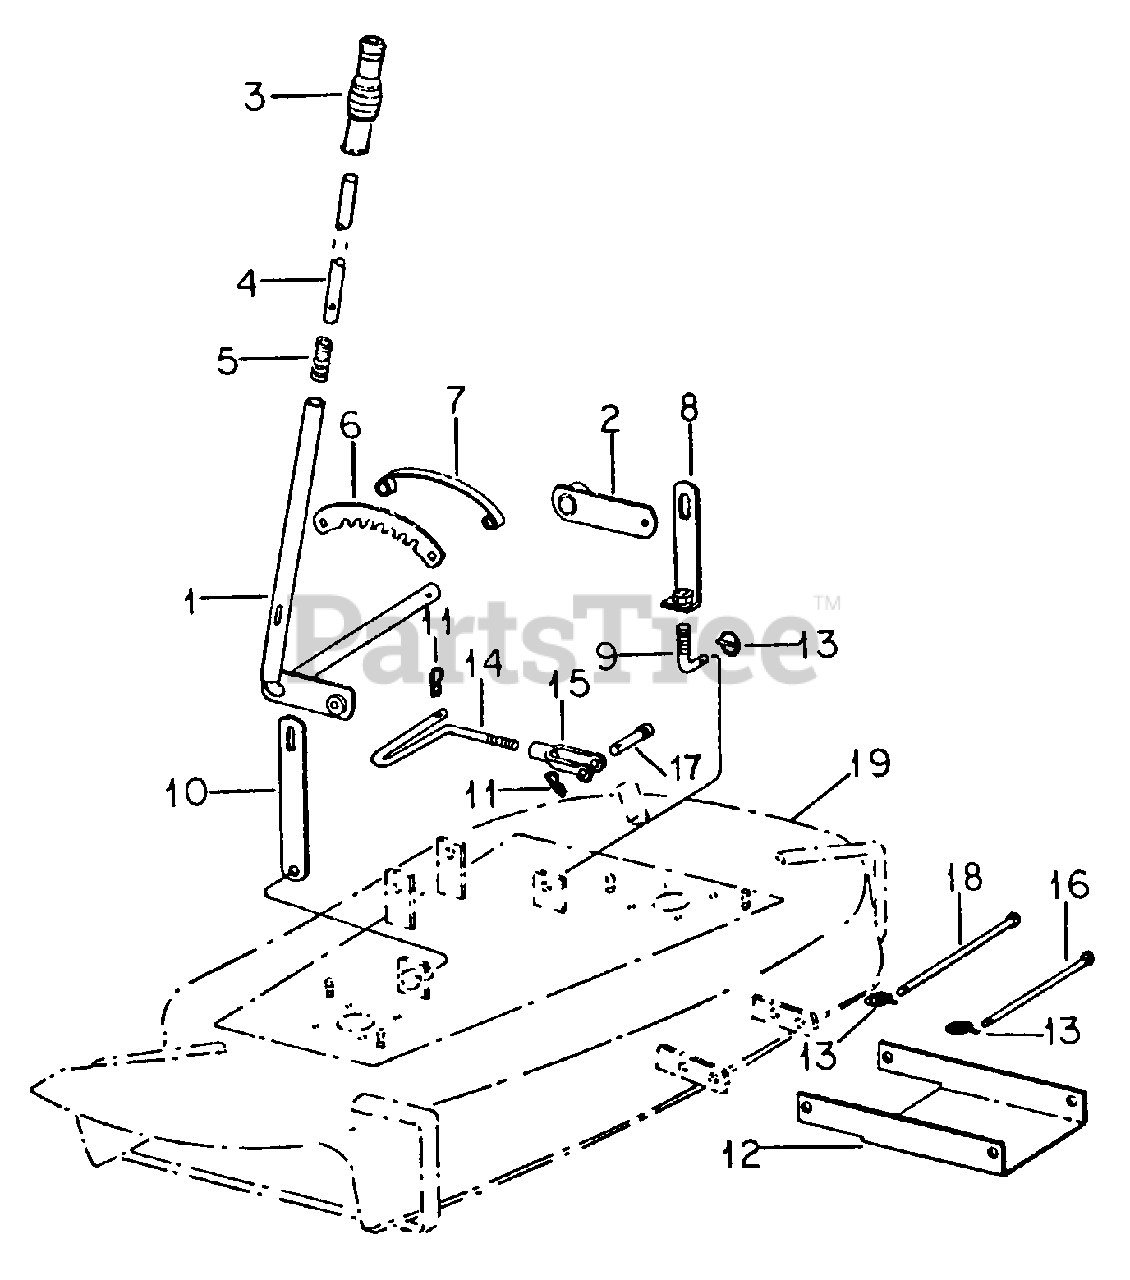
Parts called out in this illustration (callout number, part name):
1	Handle Assy, Lift
2	Arm Assy, Lift Handle, LH
3	Grip, Lift Handle
4	Button, Lift Handle
5	Spring, Lift Button
6	Ratchet, Lift
7	Spacer, Ratchet
8	Support Assy, Lift - Link
9	Rod, Lift Link
14	Rod, Mower Linkage
15	Clevis, Short Adj Rod End
16	Pin, 1/2 X 7.688 Std Hd
17	Pin, 1/2 X 2-3/32 Rod End
18	Pin, 1/2 X 7 Znd Std Hd
19	Housing Assy, Mower - Refer to Mower Listing
